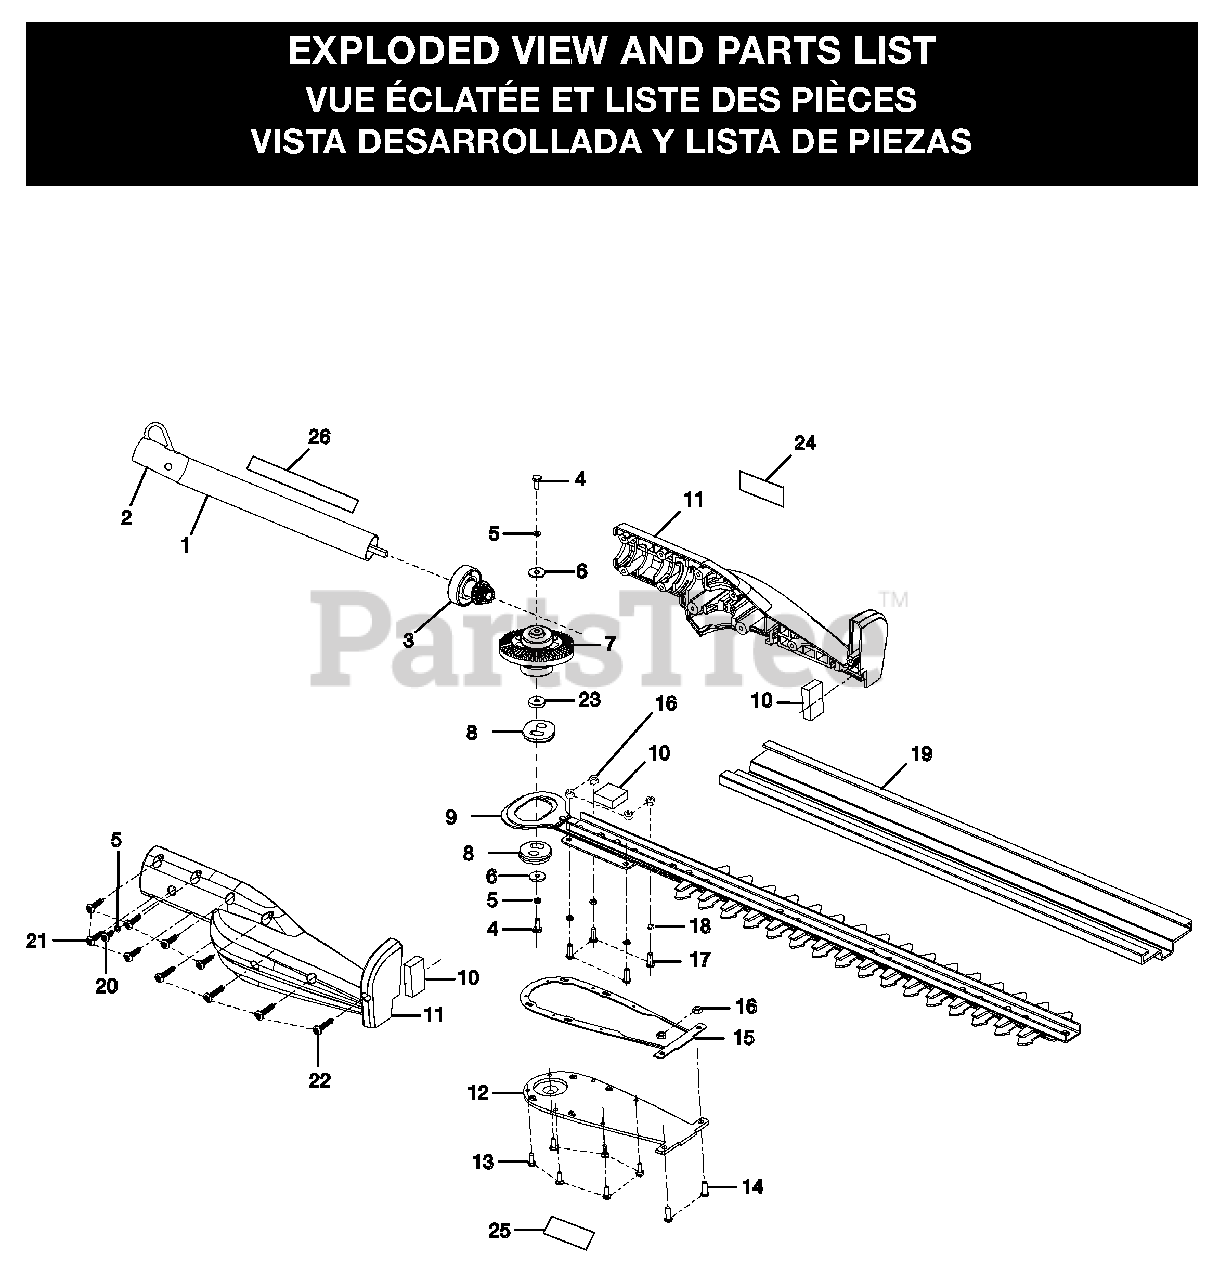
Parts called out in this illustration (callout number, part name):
1	Lower Drive Shaft Assembly
2	Hanger Cap
3	Pinion Assembly
4	Screw (M5 x 10 mm)
5	Spring Washer (M5)
6	Washer (M5)
7	Output Gear Assembly
9	Blade Assembly
10	Felt
11	Housing Assembly
12	Housing Bottom Plate
13	Screw (M3 x 8 mm)
14	Screw (M4 x 12 mm)
15	Seal
16	Nut (M4)
17	Screw (M4 x 16 mm)
18	Spring Washer (M4)
19	Scabbard
20	Screw (M4 x 9 mm)
21	Screw (M5 x 14.5 mm)
22	Screw (M5 x 26.5 mm)
23	Cam Spacer
24	Logo Label
25	Hot Surface Label
26	Warning Label
